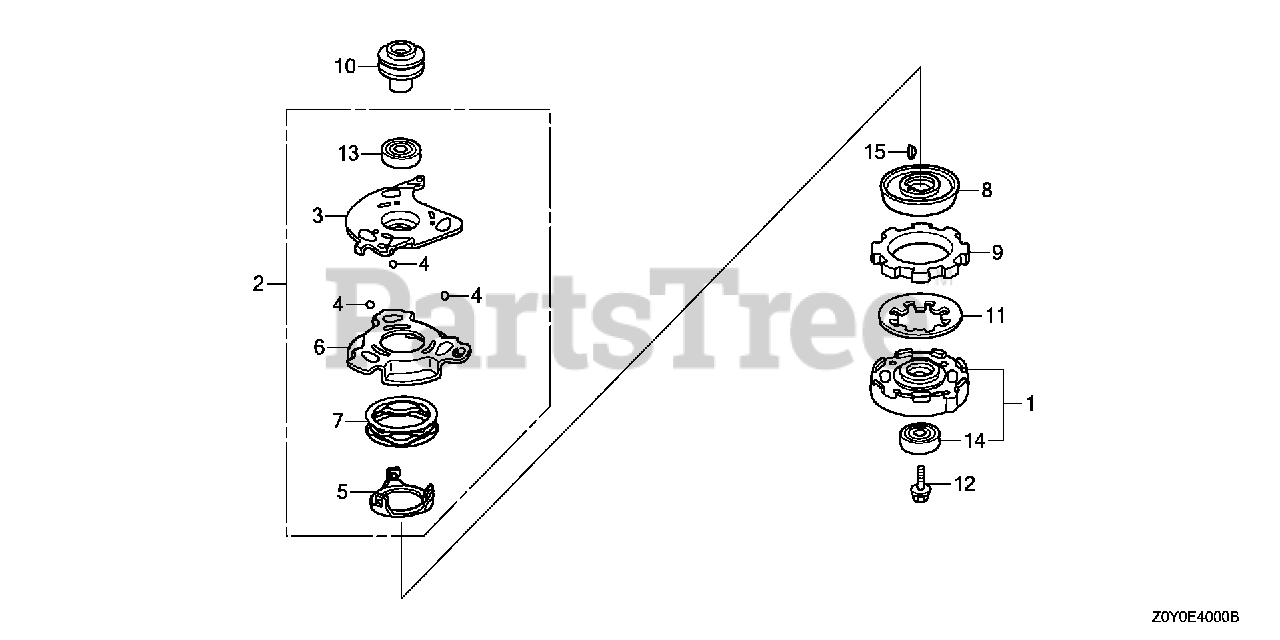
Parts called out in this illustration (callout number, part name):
1	HOLDER ASSY., BLADE
2	PLATE ASSY., BALL CONTROL
3	PLATE, BALL CONTROL
4	BALL, STEEL
5	PLATE, SPRING HOOK
6	PLATE, BRAKE
7	SPRING, BALL PLATE
8	DISK, DRIVE
9	DISK, DRIVEN
10	PULLEY, DRIVE
11	SPRING, CLUTCH
12	BOLT, FLANGE (10X24)
13	BEARING, RADIAL BALL (6006) (SST)
14	BEARING, RADIAL BALL (6204)
15	KEY, WOODRUFF (16X15)
